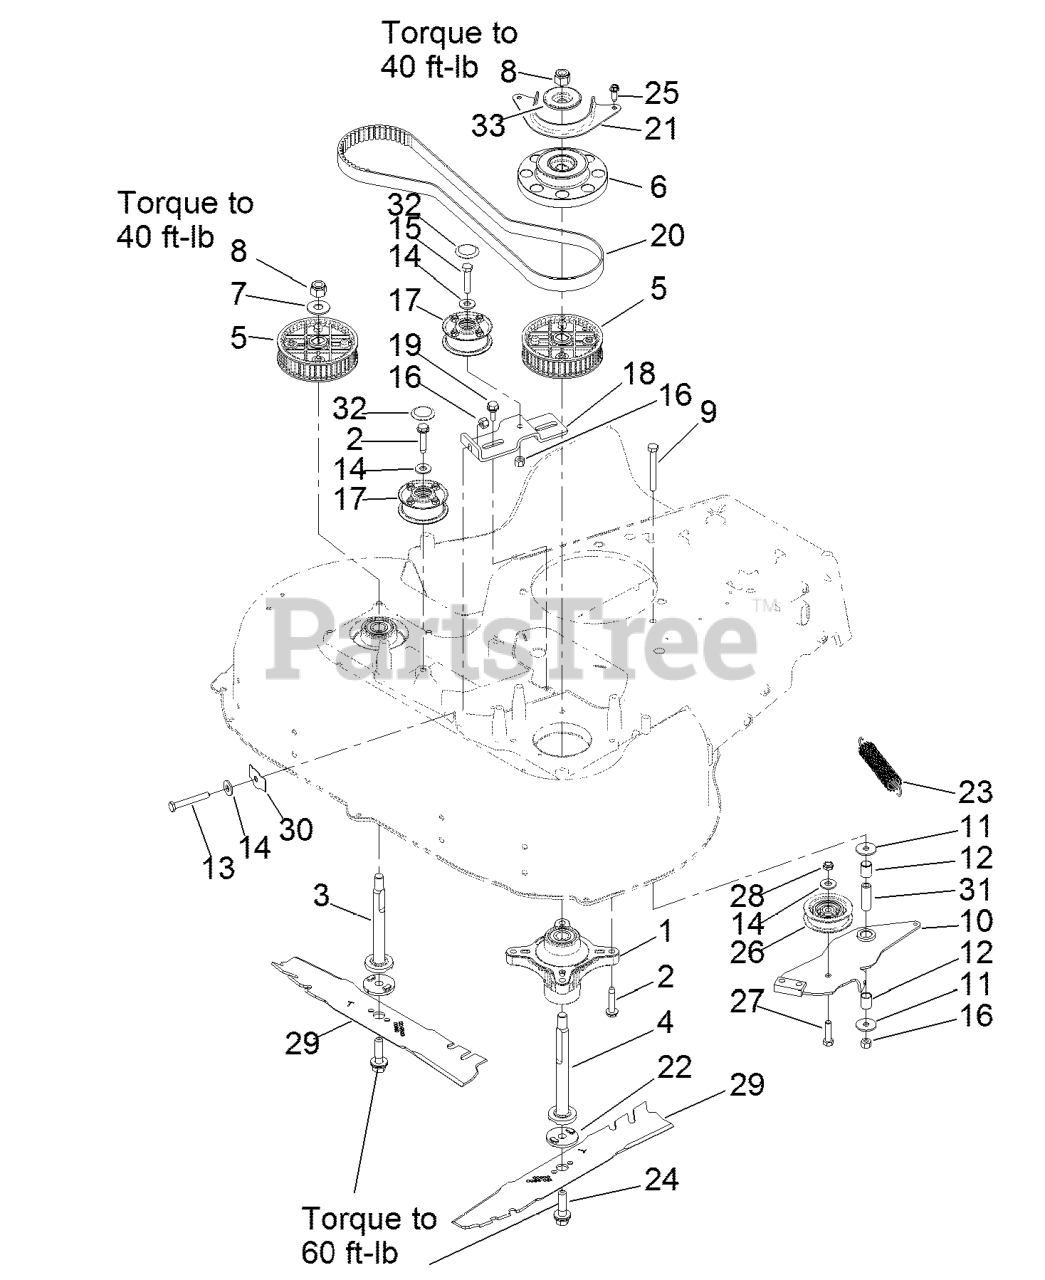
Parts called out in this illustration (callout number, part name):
1	SPINDLE ASM
3	SHAFT-SPINDLE
4	SHAFT-SPINDLE
5	SPROCKET
6	PULLEY-BRAKE, SPINDLE
7	WASHER-SPRING
8	NUT-HEX
9	SCREW-HH
11	WASHER-PIVOT
12	BUSHING-SLEEVE
13	BOLT-TAP, HH
14	WASHER-FLAT
15	SCREW-HH
16	NUT-LOCK, NI
18	BRACKET-IDLER
19	SCREW-SHOULDER,HWH
20	BELT-SYNCHRONOUS
21	GUIDE-BELT, SPINDLE
22	ADAPTER-BLADE
23	SPRING-EXTENSION, BRAKE
24	BOLT-BLADE
25	SCREW-HWHTF
26	PULLEY-IDLER
27	SCREW-HH
28	NUT-LOCK, NI
29	BLADE-ROTARY
30	SPRING-FLAT
32	PLUG-CAP
